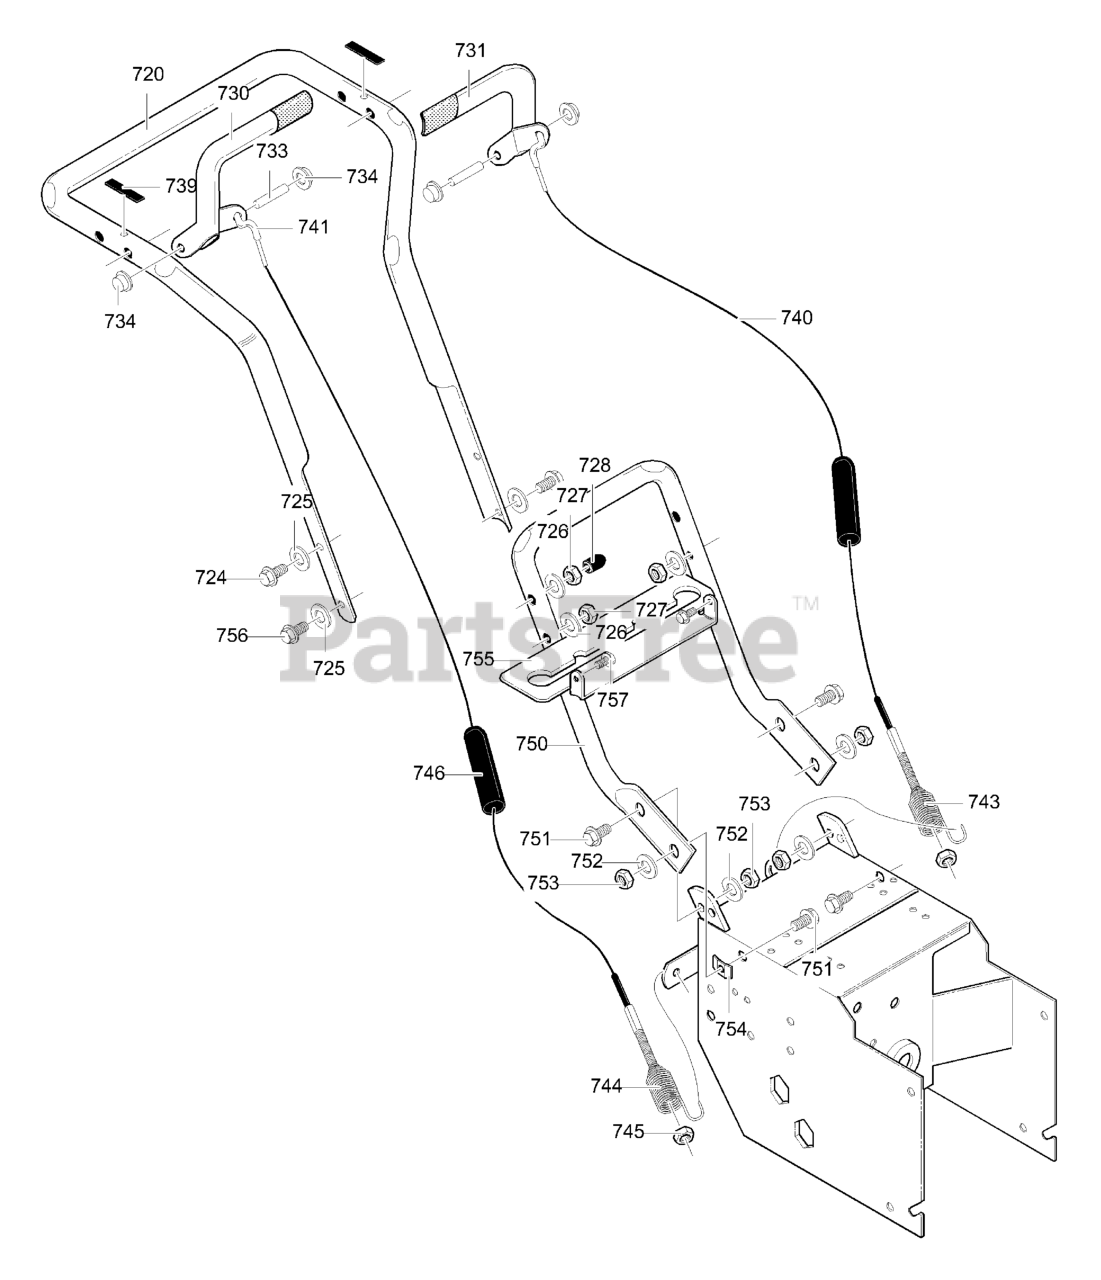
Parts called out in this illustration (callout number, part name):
720	HANDLE, UPPER
724	SCREW, 5/16-18 x 2.75
725	WASHER, FLAT
726	WASHER
727	NUT, 5/16-18 REGHEX
728	STOP, RED PLASTIC
730	CLUTCH HANDLE RH
731	CLUTCH HANDLE LH
733	PIN, CLUTCH HANDLE
734	NUT, PUSH ON CAP
739	BUMPER, RECTANGLE
740	CABLE, CLUTCH 28.44L
741	CABLE, AUGER CLUTCH
743	TENSION SPRING
744	SPRING, AUGER CLUTCH
745	NUT, 1/4-20
746	BOOT, CLUTCH SPRING
750	HANDLE, LOWER
751	CAPSCREW, Hex Head, 5/16-18 x 1
752	WASHER, SPTLK
753	NUT, 5/16-18 REGHEX
754	PUSHNUT, 5/16 BOLT RETAINER
755	BRKT, GEAR SELECTOR
756	SCREW, 5/16-18 x 2.00
